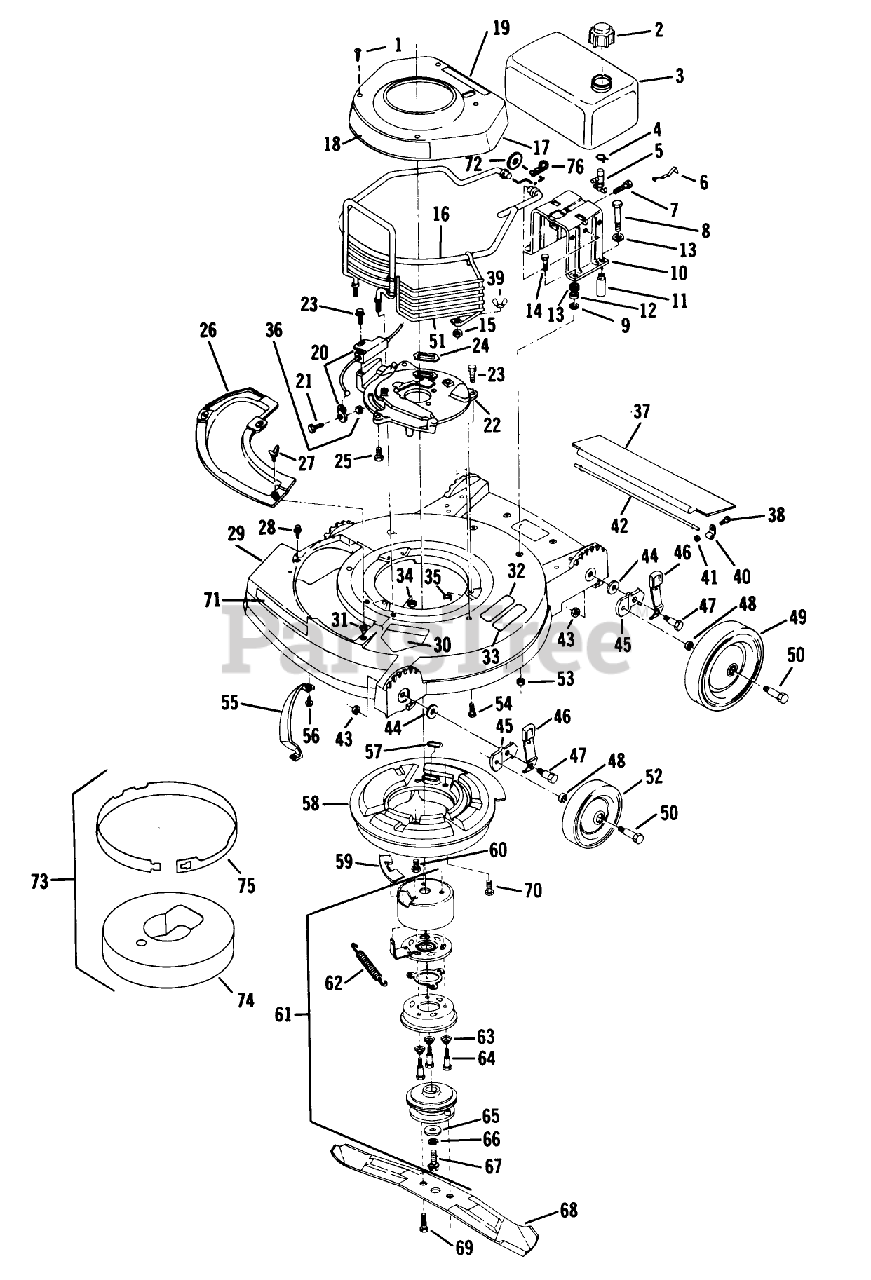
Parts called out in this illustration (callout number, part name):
1	SCREW - SELF TAPPING
2	FUEL CAP & INSERT
4	CLAMP - HOSE S
5	VALVE&SCREEN SM
6	SPRING
7	SCREW S
9	WASHER
13	WASHER
14	BOLT PIONEER
15	LOCKNUT E
17	SHROUD S
23	SCREW-HH
25	SCREW V
27	WING SCREW LAWRE
33	PAD FOOT
34	NUT-LOCK F
35	NUT-LOCK F
36	LOCKNUT E
37	T/SHIELD GEAUGA
40	CLAMP ROD KMC
41	LOCKNUT E
42	ROD 21" ADVANCE
43	Nut
44	WASHER
47	BOLT
48	WASHER WROUGHT
49	WHL & TIRE AY
50	BOLT-SHOULDER
52	WHEEL & TIRE ASSY
53	LOCKNUT E
54	Screw
55	BAR-TOE
57	SEAL
60	SCREW
62	SPRING
64	SCREW,SHOULDER SM
65	WASHER
69	SCREW SEMS
72	WASHER SPRING LAR
76	HAIR PIN
